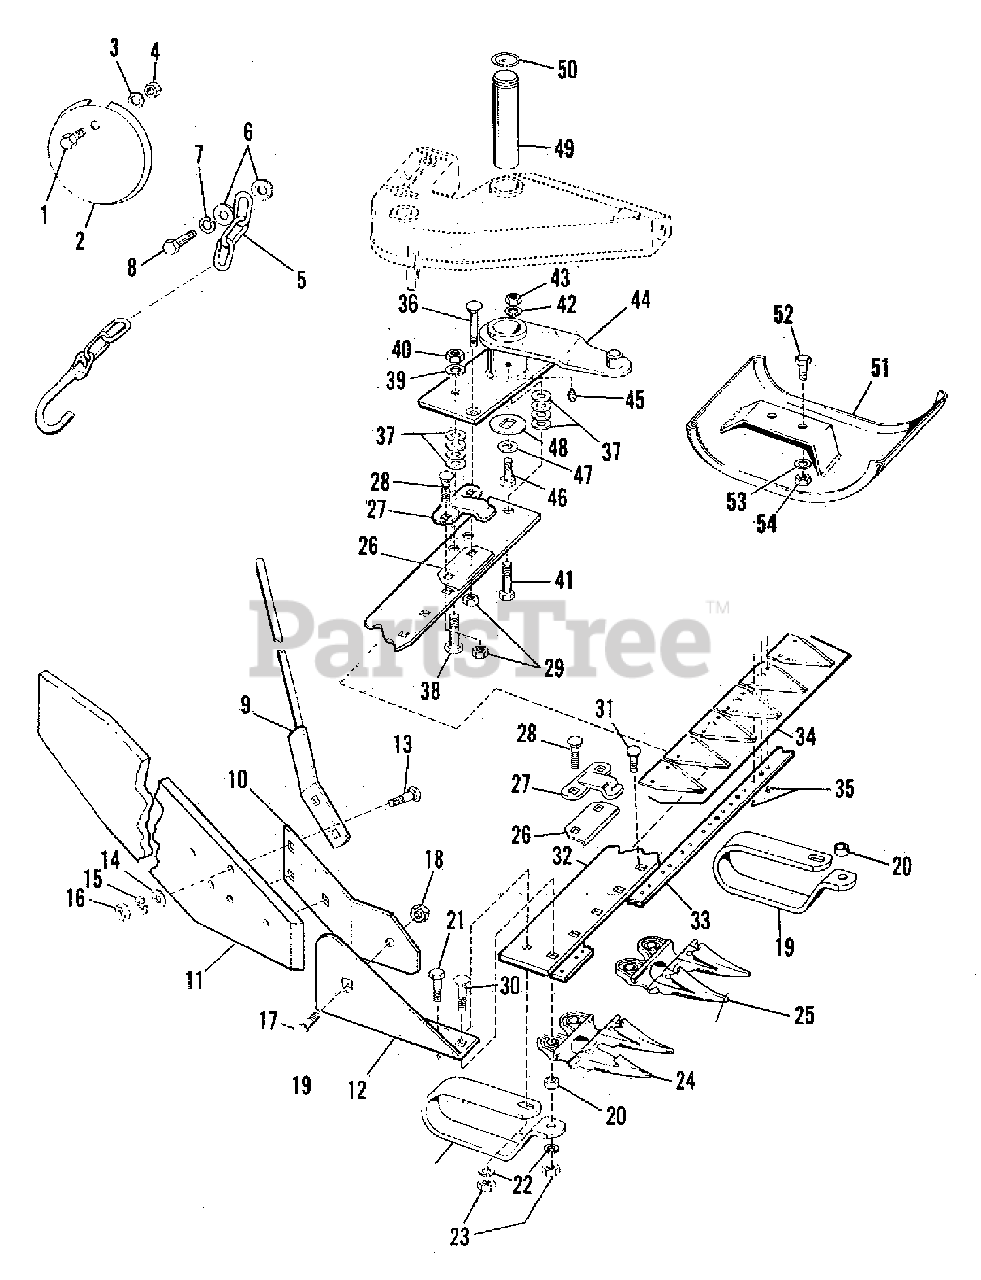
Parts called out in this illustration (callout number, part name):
1	CAPSCREW, Hex Head, 3/8"-16 x 1" Lg.
2	GUARD, Clutch Pedal
3	WASHER, Lock, 3/8"
4	NUT, Hex, Full, 3/8"-16
5	CHAIN ASSEMBLY, Transport
6	WASHER, Plain, 3/8"
7	WASHER, Lock, 3/8"
8	CAPSCREW, Hex Head, 3/8"-16 x 1-1/4" Lg.
9	DIVIDER ROD ASSEMBLY
10	SUPPORT, Divider Board
11	BOARD, Divider
13	BOLT, Carriage, 3/8"-16 x 1-1/2" Lg.
14	WASHER, Plain, 3/8"
15	WASHER, Lock, 3/8"
16	NUT, Hex, Full, 3/8"-16
17	BOLT, Carriage, 3/8"-16 x 1" Lg.
18	NUT, Hex, Full, Elastic Stop Nut, 3/8"-16
21	CAPSCREW, Hex Head, 3/8"-16 x 1-1/4" Lg.
22	WASHER, Lock, 3/8"
23	NUT, Hex, Full, 3/8"-16
24	GUARD, Right End
25	GUARD, Twin
26	PLATE, Wear
27	CLIP, Sickle
28	BOLT, Carriage, 3/8"-16 x 1-1/4" Lg.
29	NUT, Hex, Full, 3/8"-16
30	BOLT, Carriage, 3/8"-16 x 1-3/4" Lg.
31	BOLT, Carriage, 3/8"-16 x 1" Lg.
32	BAR, Cutter
33	SICKLE BAR, Complete
34	COMPLETE SET OF SECTIONS
35	RIVET, Round Head, No. 6 x 1/2" Lg.
36	BOLT, Plow, 3/8"-16 x 1-3/4" Lg.
37	WASHER, Plain, 3/8"
38	CAPSCREW, Hex Head, 3/8"-16 x 1-1/2" Lg.
39	WASHER, Lock, 3/8"
40	NUT, Hex, Full, 3/8"-16
41	CAPSCREW, Hex Head, 7/16"-14 x 1-1/2" Lg.
42	WASHER, Lock, 7/16"
43	NUT, Hex, Full, 7/16"-14
44	LEVER ASSEMBLY, Cutter Bar
45	FITTING, Grease
46	CAPSCREW, Hex Head, 3/8"-16 x 1" Lg.
47	WASHER, Plain, 3/8"
49	CUTTER BAR SHAFT
50	RING, Retaining
51	SHOE ASSSEMBLY
52	CAPSCREW, Hex Head, 3/8"-16 x 1" Lg.
53	LOCKWASHER, 3/8"
54	NUT, Hex, Full, 3/8"-16
